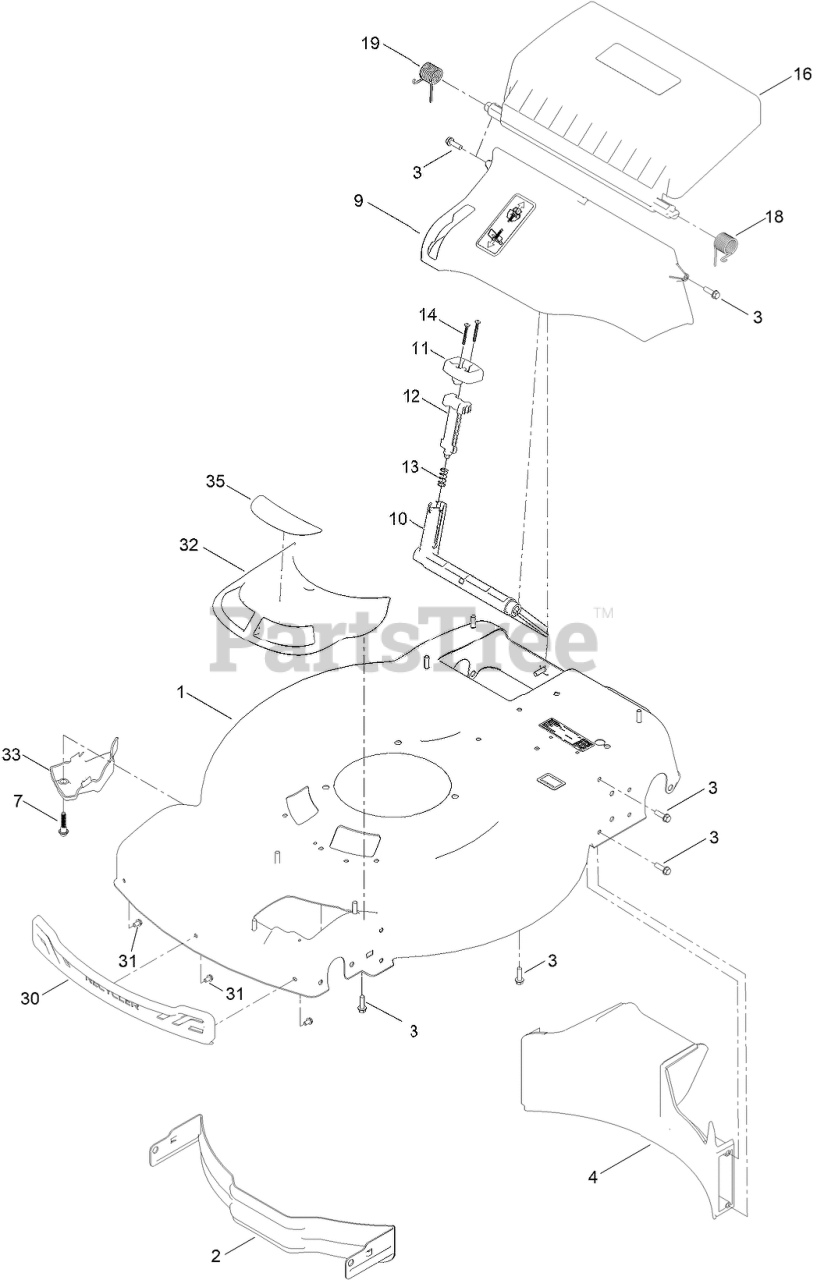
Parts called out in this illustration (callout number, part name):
1	HOUSING ASM
2	BAFFLE-FRONT
3	SCREW-PLASTITE, HWH
4	BAFFLE-REAR, RWD
7	SCREW-SHOULDER, HHF
9	ASM-CHUTE, IN MOLD
10	DEFLECTOR-RECYCLE
11	KNOB-RECYCLE
12	LATCH-RECYCLE
13	SPRING-COMPRESSION
14	SCREW-PPH
16	ASM-REAR DOOR, IN MOLD
18	SPRING-TORSION, LH
19	SPRING-TORSION, RH
30	BUMPER-FRONT
31	SCREW-PLASTIC, HWH
32	ASM-INTAKE, RWD
33	COVER-INTAKE, BOTTOM
35	DECAL-VORTEX RWD
